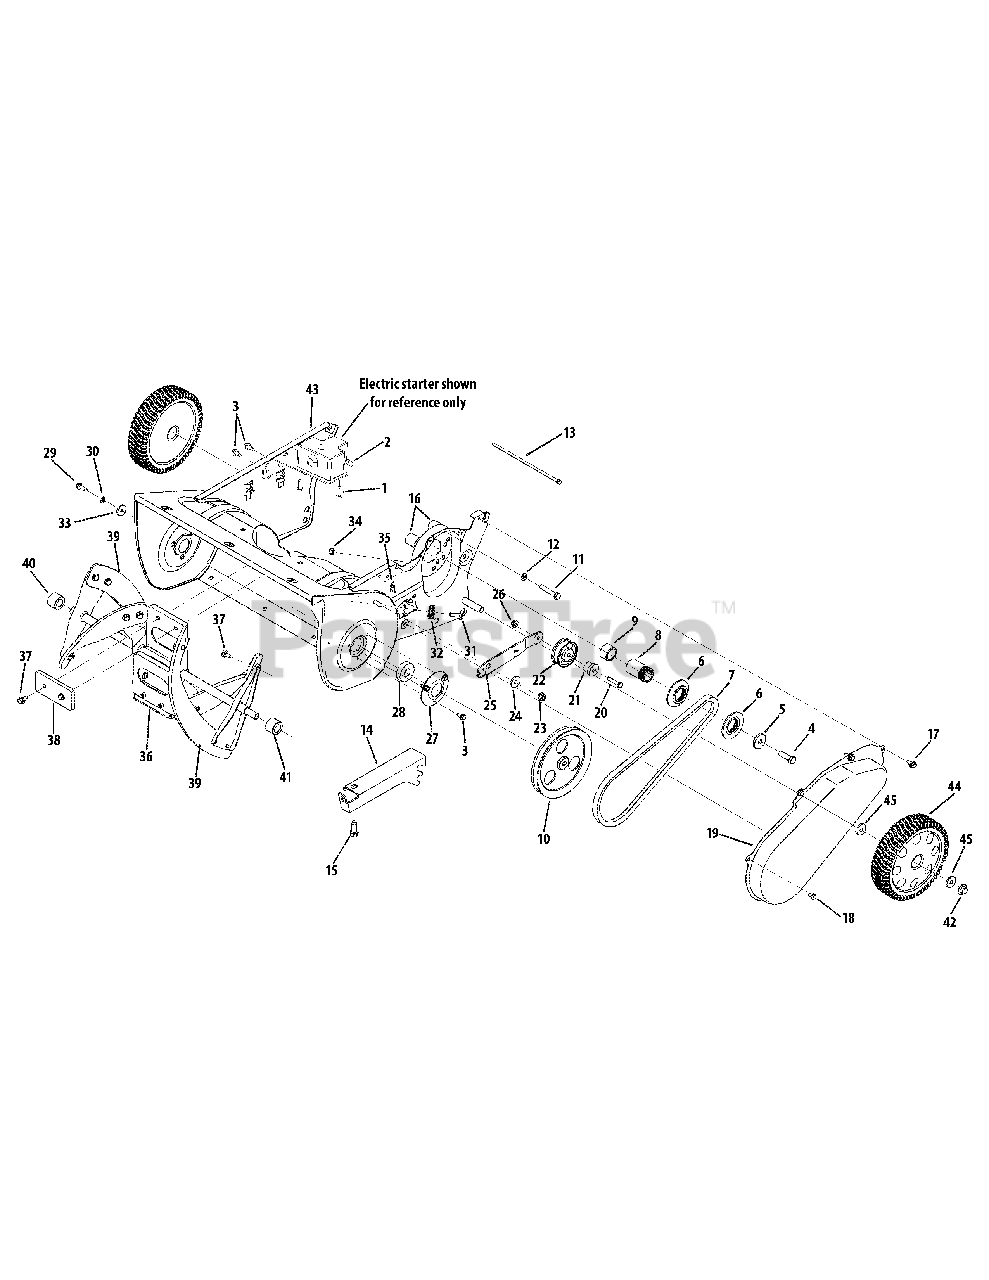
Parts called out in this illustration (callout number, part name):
1	Hex Screw, #12-16 x .75
2	Electric Starter Support Bracket
3	Hex Screw, 1/4-14 x .500
4	Hex Screw, 3/8-24 x 1.75
5	Flat Washer, .406 x 1.25 x .157
6	Pulley Half, 4L-V x 2.30 OD
8	Spacer, .875 ID x 1.185 OD
9	Spacer, .88 ID x 1.18 OD x .74 Lg.
10	V-Type Pulley, 1/2 x 35.7
11	Hex Screw, 5/16-24 x 1.75
12	Lock Washer, 5/16
13	Cable Tie, 7.5
14	Engine Support Bracket
15	Hex Washer Screw, 3.8-16 x 1.000
16	Spacer, .875 x .320 x 1.027
17	Hex Washer Screw, 1/4-14 x .625
18	Hex Washer Screw, 1/4-20 x .375
19	Belt Cover
20	Hex Screw, 1/4-20 x 1.25
21	Shoulder Spacer, .260 x .785 x .538
22	Pulley Assembly, 1.917 OD
23	Flange Lock Nut, 5.16-18
24	Shoulder Spacer
25	Idler Bracket w/ Brake
26	Flange Lock Nut, 1/4-20
28	Ball Bearing, 1.25 x 37 x 12.6301
29	Hex Screw, 1/4-20 x .750
30	Lock Washer, 1/4
31	Shoulder Screw, .340 x .335 x 1/4-28
32	Cable Roller
33	Flat Washer, .265 x .938 x .120
34	Hex Lock Nut, 1/4-28
35	Extension Spring, .33 OD x 1.12
36	Auger Assembly, 21 inch
37	Hex Screw, 1.4-14 x .625
38	Rubber Pad
39	Spiral Crescent
42	Push Cap, 1/2 inch
43	Auger Housing
44	Wheel, 8 x 2
45	Flat Washer, .510 x 1.000 x .125
